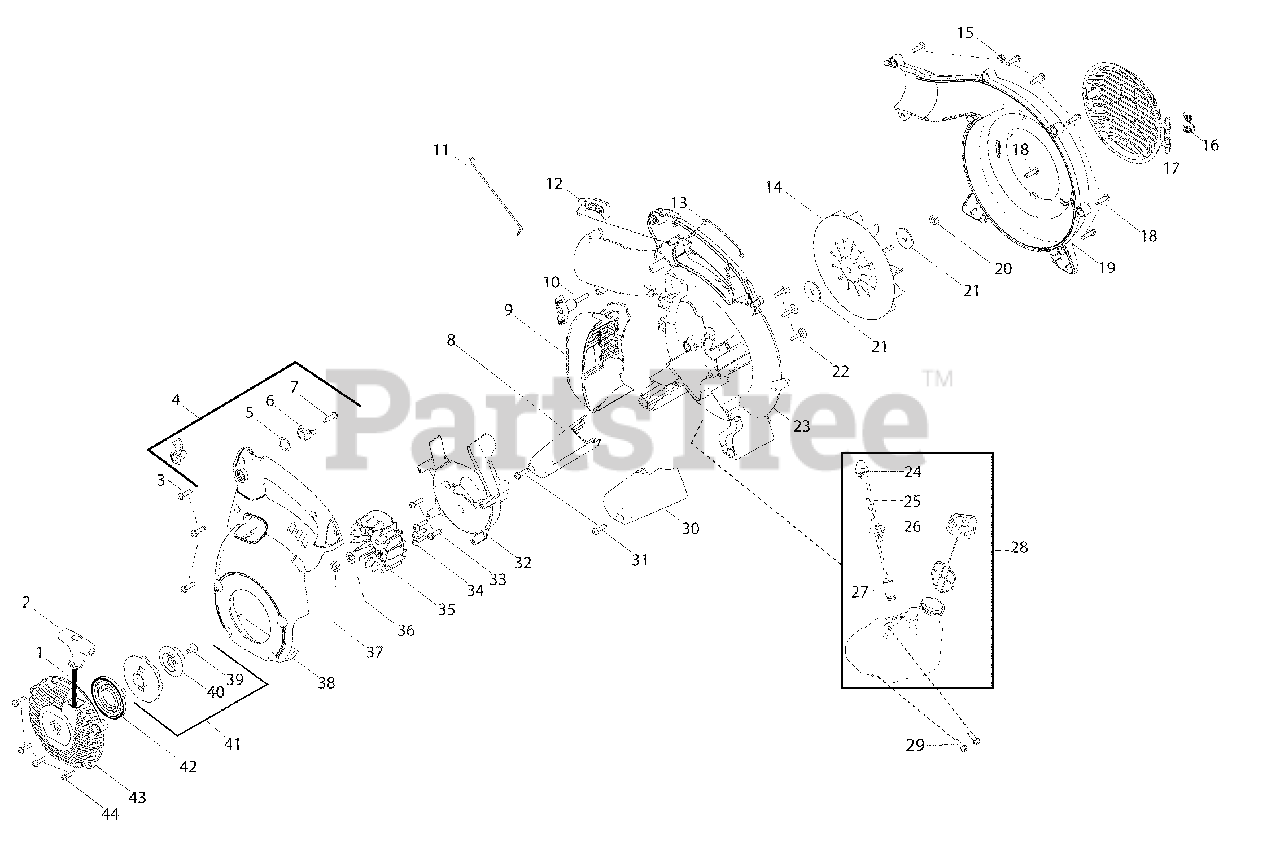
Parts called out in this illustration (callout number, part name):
1	Kit - Rope
2	Handle - Starter
4	Kit - Cruise Control
5	Washer - Wave
6	Ratchet - Cruise Control
8	Foot - Front Impact
9	Assy. - Muffler Guard
10	Assy - Blower Knob
11	Wire - Linkage
12	Trigger - Throttle
13	Wire - Handle Ground
14	Impeller
15	Nut - Blower Tube Knob
16	Spring - Vac Door
17	Cover - Vac Door
19	Assy - Outer scroll
20	Nut - Impeller
21	Washer - Impeller
23	Scroll - Inner
24	Bulb - Purge
25	Kit - Fuel line grommet
26	Assy - Fuel cap with retainer
27	Assy - Fuel pickup
28	Assy - Fuel tank
29	Screw - Fuel tank
30	Foot - Rear Impact
32	Scroll - Flywheel
34	Screw
35	Assy - Flywheel
37	Nut - Flywheel
38	Cover - Motor housing
41	Kit - Starter
42	Spring - Starter
43	Housing - Starter Cover
44	Screw
